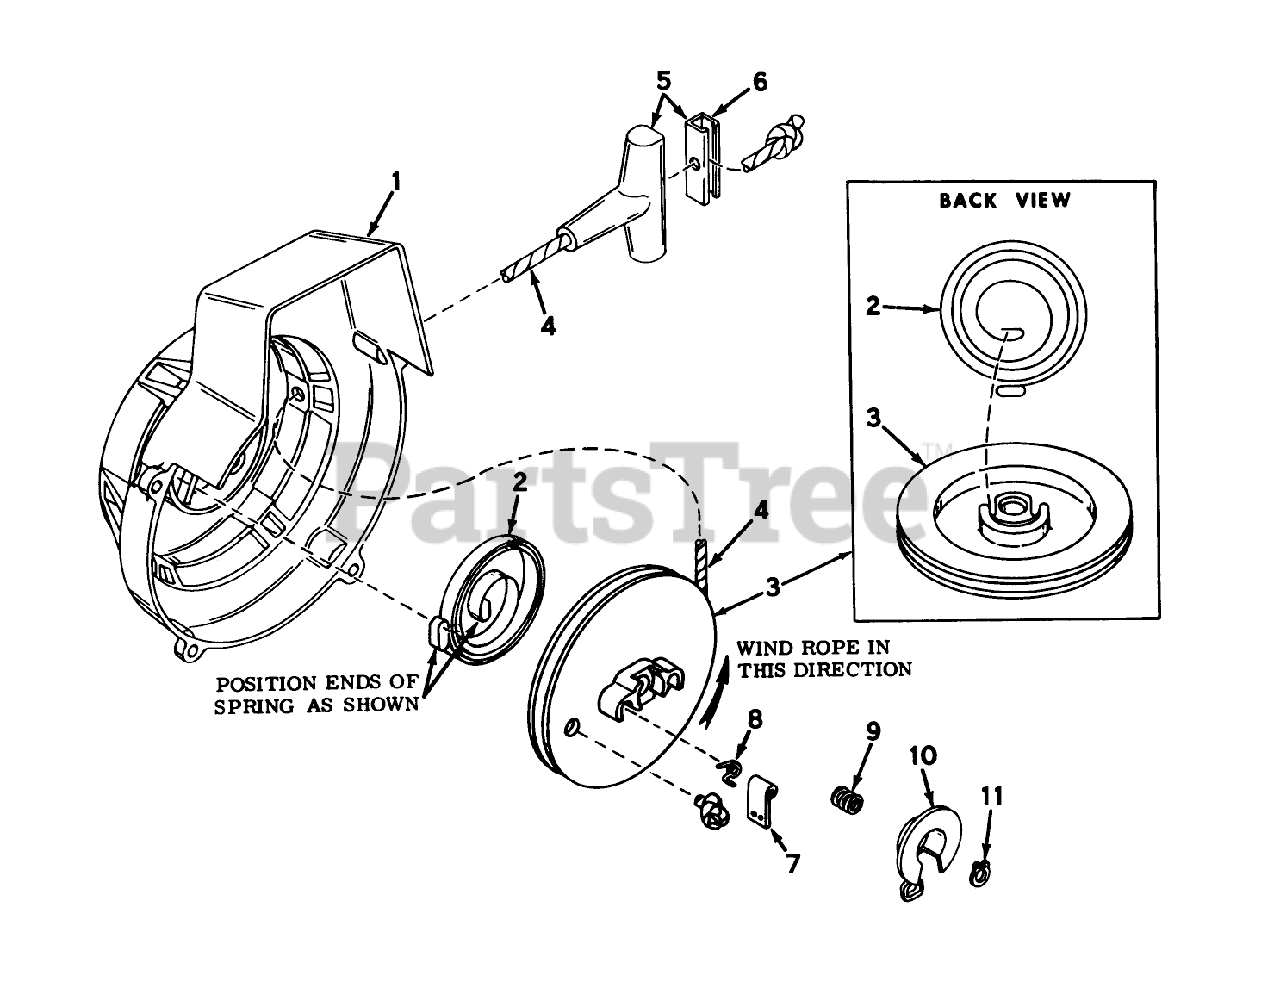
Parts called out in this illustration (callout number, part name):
1	Housing Assy., Shroud Starter
2	Spring, Rewind
3	Pulley, Starter Rope(Incl. No. 8)
4	Rope-Starter
5	Assy., Starter
6	Insert, Handle
7	Dog, Starter
8	Retum Spring, Left Hand Wound
9	Spring, Brake
10	Brake
11	E Ring Truarc
